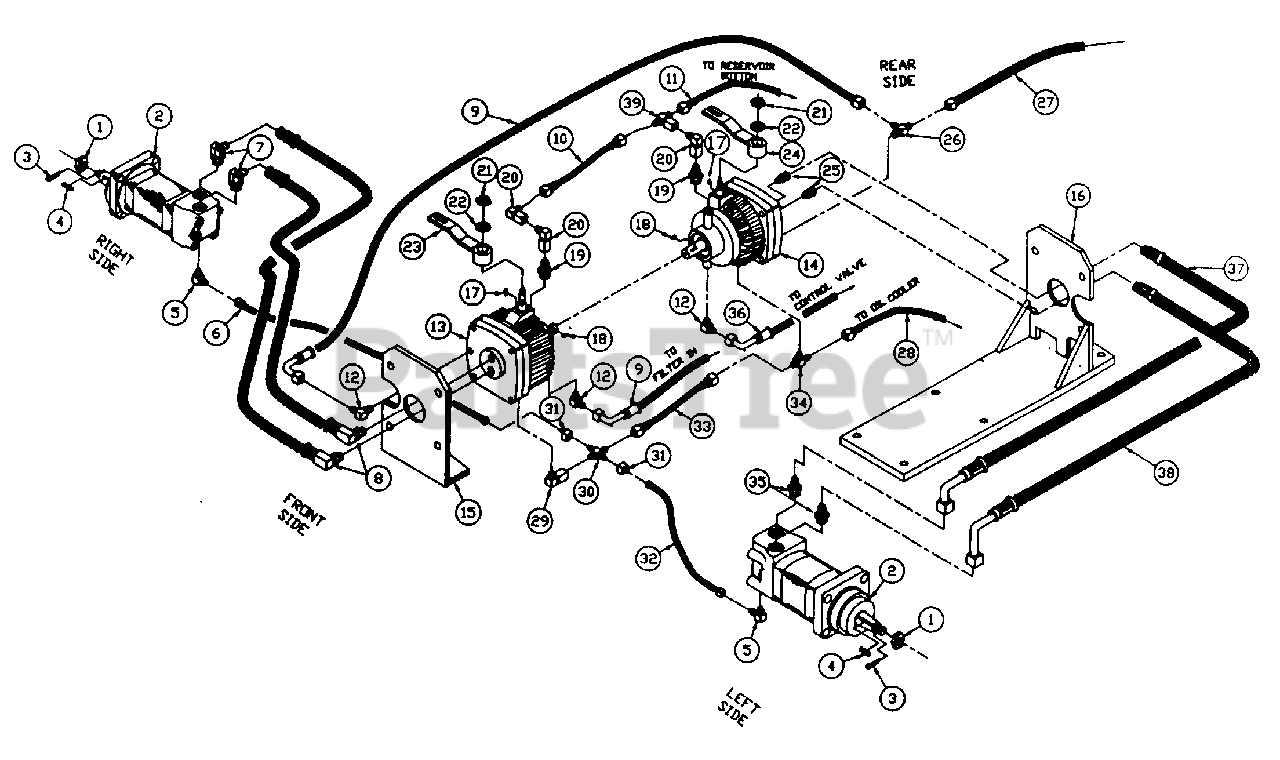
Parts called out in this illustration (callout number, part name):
2	Wheel Motor, Liquid-cooled
3	Cotter Rey, 3/16" x 1 3/4"
5	Male Tube, 90ø Adj. O-ring Adpt.
6	Hose Ass'y. 1/4" LD x 5 1/4"
7	Male Tub, 90ø Adj. O-ring Adpt.
8	Hose Ass'y., 1/2" ID x 19"
9	Hose Ass'y., 3/8" ID x 30"
10	Hose Ass'y., 5/8" ID x 4 1/2"
11	H08e AJJ'Y., 3/4" ID x 21"
12	Male Tub, 90ø Adj. O-ring Adpt.
13	Pump, LH
14	Pump, RH.
15	Trans Pump Mount End
16	Trans Pump Mount
17	Woodruff Key, 1/8" x 5/8"
19	Male Tube, Male O-ring dpt.
20	Male Tub, 90ø Female Swivel Adpt.
21	Hex Nut, 1/2-13 0
22	Lockwasher, 1/2"
23	Stcerlng Arm, RL
24	Steerlng Arm, LH
25	Male O-rlng, Female Pipe Swivel Adpt.
26	Male Tube, Male O-rlng Tee
27	Hose Ass'y., 3/8" ID x ll 1/2"
28	Hose Ass'y., 1/2" ID x 29"
29	Adt. Male O-rlng, 90ø Female Swlvel Adpt.
30	Male Tube Cross
31	Female Tube, Male Tube Reducer
32	Hose Ass'y., 1/4" ID x 20"
33	Hose Ass'y.1/2" ID x 5 3/4"
34	Male Tube, d. Male O-rlng Tee
35	Male Tube, Male O-rlng Adpt.
36	Hose Ass'y. 3/8" ID x 42"
37	Hose Ass'y., 1/2" ID x 42"
38	Hose Assy. 1/2" ID x 42"
39	Male Tube, Female Swivel Tee
